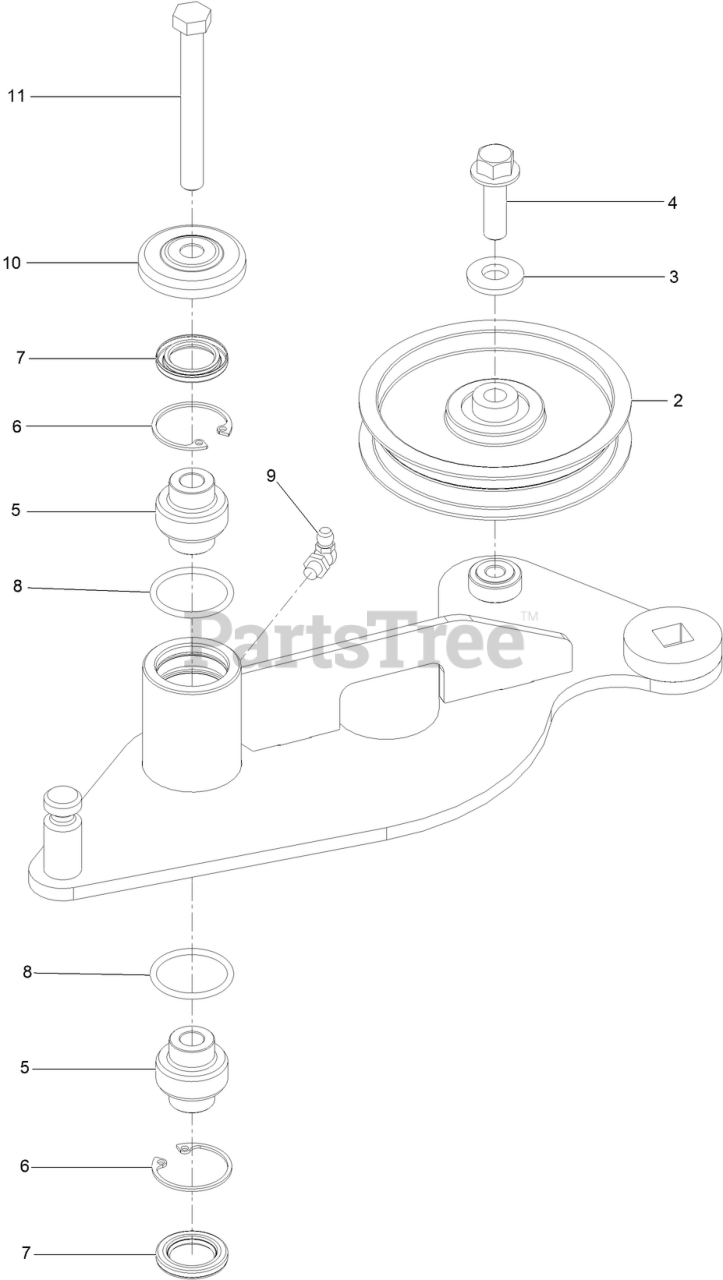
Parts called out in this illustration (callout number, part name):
3	WASHER-BELLEVILLE
4	SCREW-HHF
5	BEARING-SPHERICAL
6	RING-SNAP
7	SEAL-LIP, SINGLE
9	FITTING-GREASE, 90 DEG
10	GUARD-TOP
11	SCREW-HH
